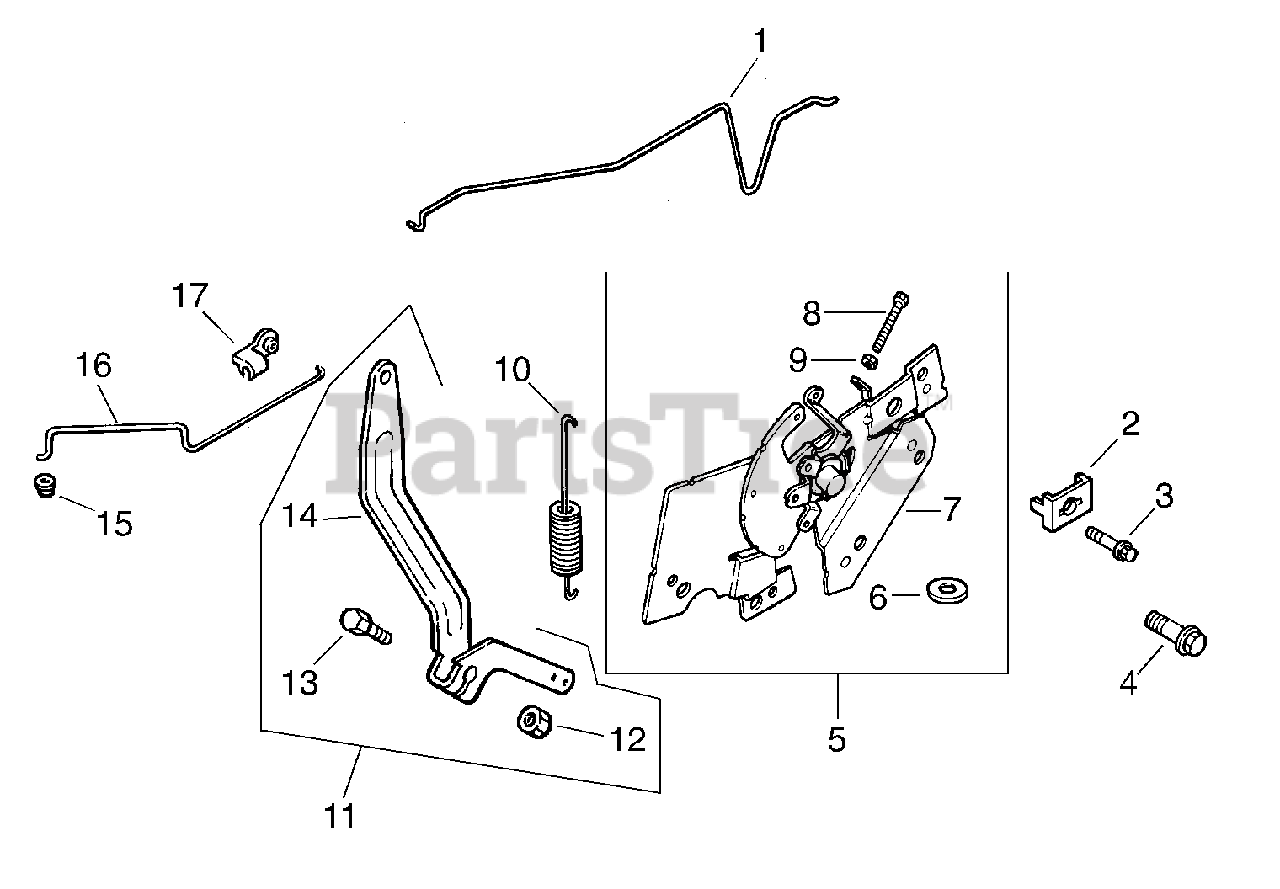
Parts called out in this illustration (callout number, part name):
1	Linkage, Choke
2	Clamp, Cable
3	Screw, Hex. Flange M5 x 0.8 x 16
4	Screw, Lobed Socket M6 x 1.0 x 20
5	Control, Speed Assembly
6	Spacer, Shim .005
7	Bracket, Control (Model 1517)
8	Screw, Hex. Flange M4 x 0.7 x 30
9	Nut, Hex. M4 x 0.7
10	Spring, Governor
11	Kit, Governor Lever
12	Nut, Hex. Flange M6 x 1.0
13	Screw, Hex. Flange M6 x 1.0 x 25
14	Lever, Governor
15	Bushing, Linkage Retaining
16	Linkage, Throttle
17	Bushing, Linkage Retaining
